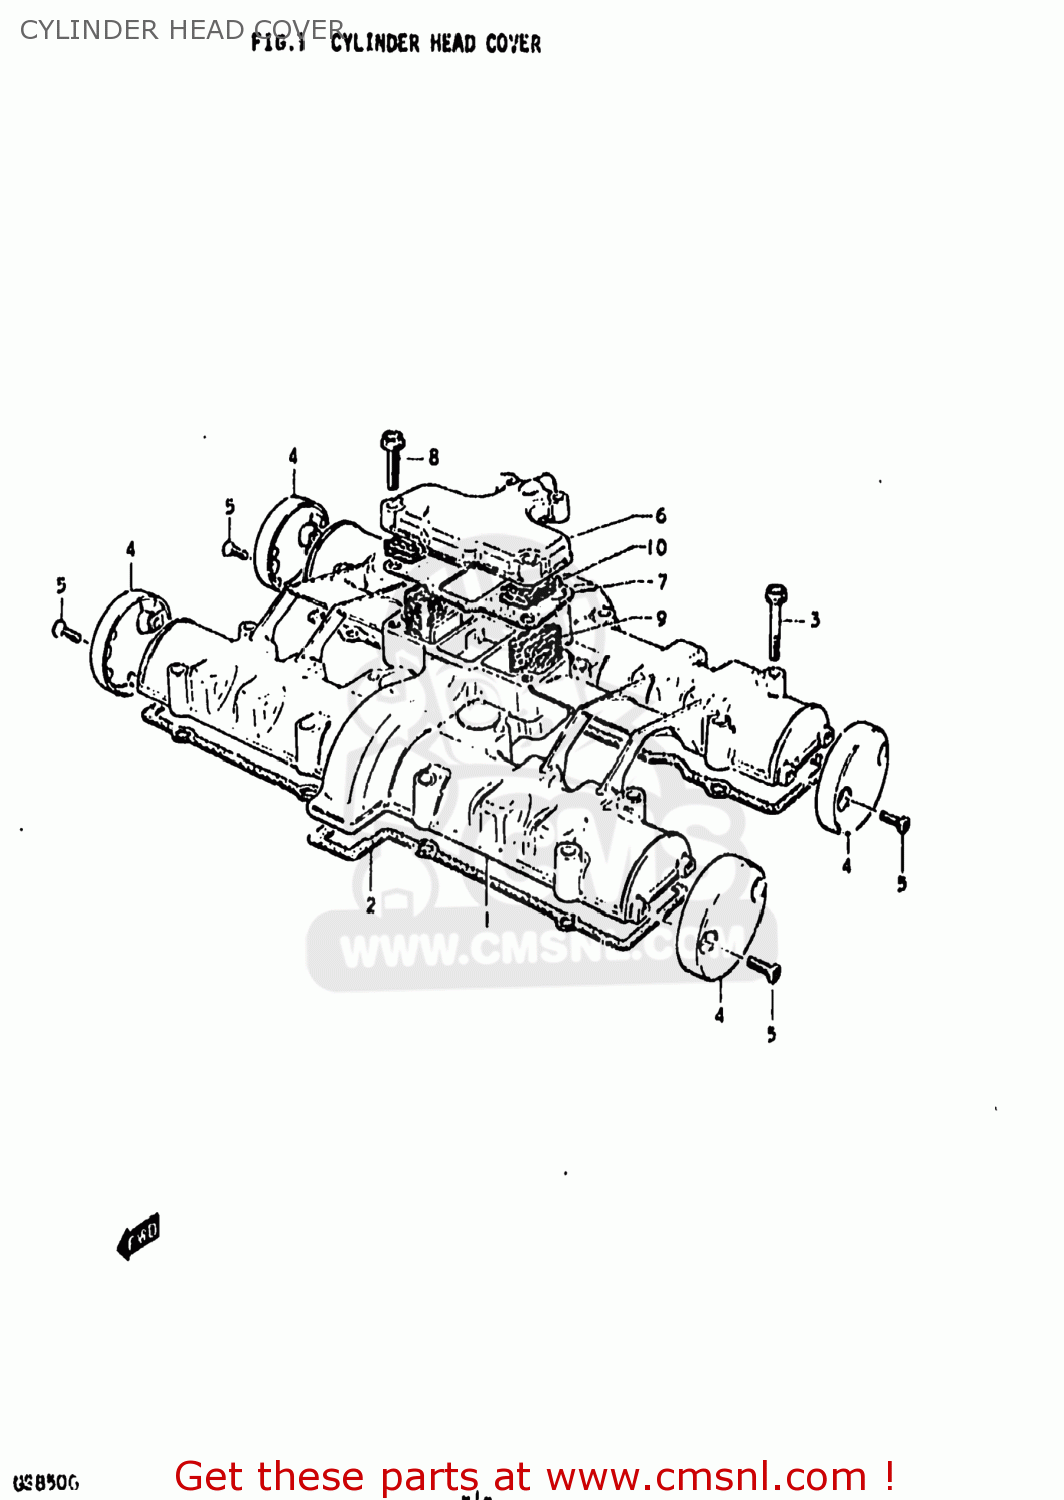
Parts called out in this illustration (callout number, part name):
1	COVER,CYLINDER HEAD
2	GASKET,CYLINDER HEAD COVER (MCA)
3	BOLT
4	CAP,CYLINDER HEAD COVER
5	SCREW
6	COVER,BREATHER
7	GASKET (MCA)
8	BOLT
9	COVER,BREATHER
10	SEPARATOR,OIL BREATHER
